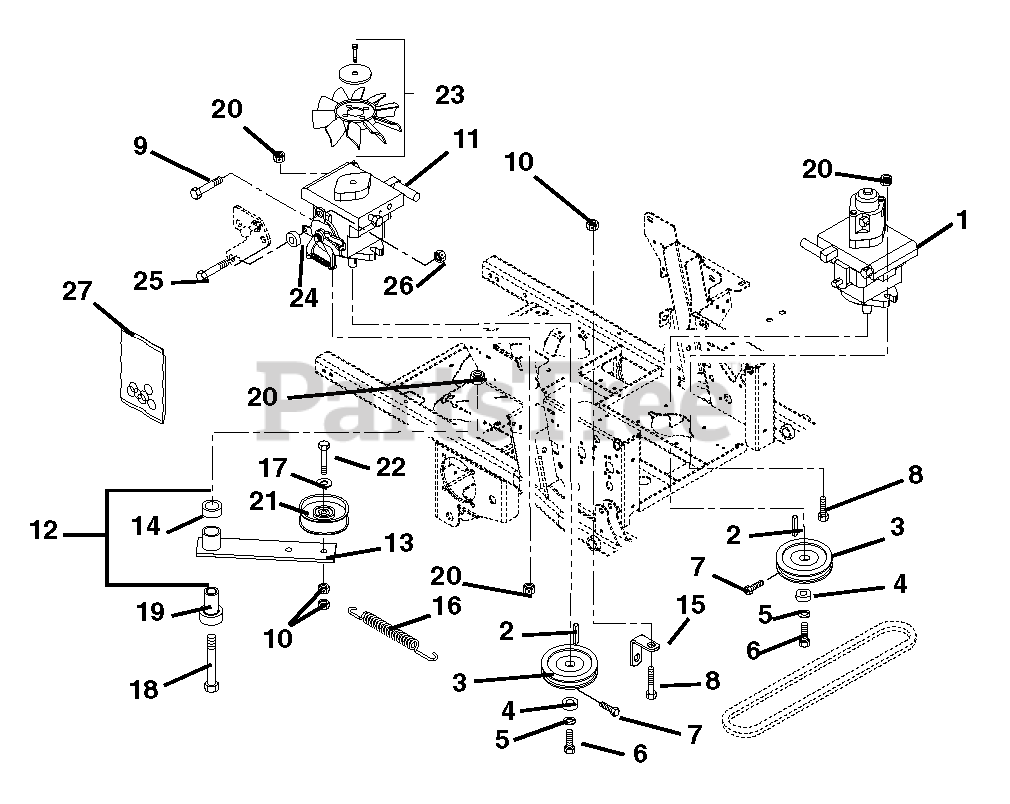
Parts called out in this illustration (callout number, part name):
1	Pump, Hydraulic with Auxiliary
2	Key, Square 5 x 5 x 30mm Plain
3	Sheave, Poly V .671 x 4.125
4	Washer, Flat Steel .281 x 1.000 x .063
5	Washer, Locking .25 x .062
6	Bolt, Hex M6 x 1.0 x 16
7	Screw, Socket Head .25-20 x .50
8	Bolt, Hex .50-13 x 1.50 Grade 5
9	Bolt, Hex .31-18 x .75 Grade 5
10	Nut-Locking-Top-Flange .38-16
11	Pump, Hydraulic BDP-21 with Thru Fan
12	Assembly, Idler Arm Guard Drive (Includes 13 & 14)
13	Weldment, Idler Arm Ground Drive
14	Bushing, 1.00 x 1.125 x 1.936
15	Anchor, Spring Idler
16	Spring, Extension
17	Washer, Flat Steel .39 x .75 x.125
18	Bolt, Hex .50-13 x 3.50 Grade 5
19	Bearing, Pedestal
20	Nut, Locking Top Flange .50-13
21	Idler, Flay 4.00 x .38
22	Bolt, Hex .38-16 x 2.25 Grade 5
23	Fan, Hydro Pump Cooling
24	Spacer .318 x .43 x .375
25	Bolt, Hex .31-18 x 1.25 Grade 5
26	Nut, Locking Top Flange .31-18
27	Kit, Pump Seal (BDP-21A)(One kit required for each pump)
